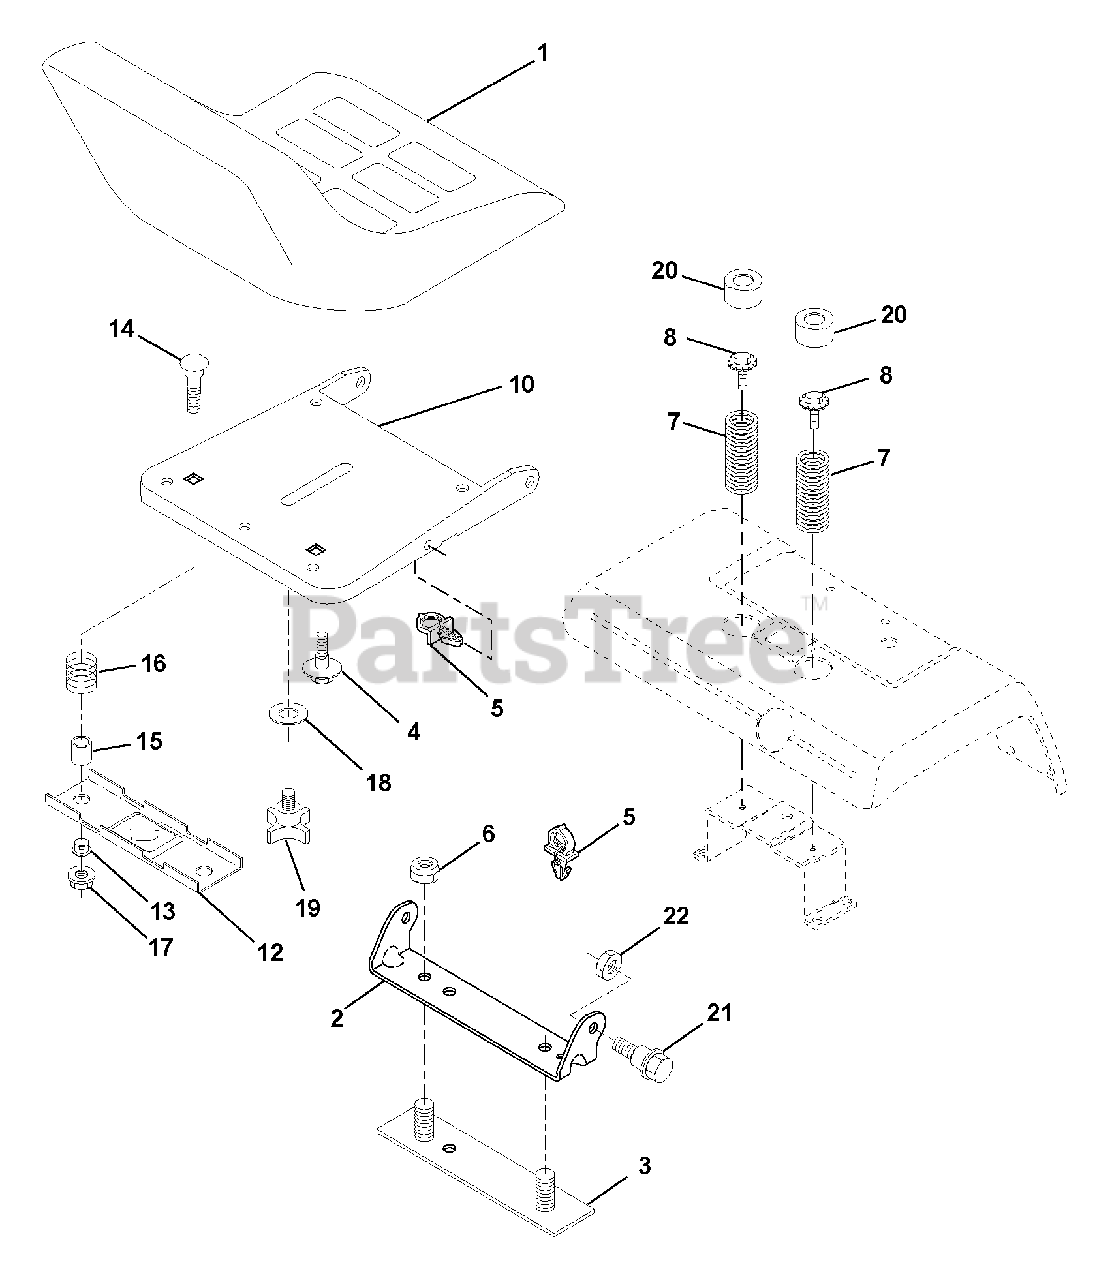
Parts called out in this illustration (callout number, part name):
1	Seat
2	Bracket, Pivot Seat
3	Strap, Fender
4	Bolt, Shoulder 5/16-18 X .62
5	Clip, Push In Hinged
6	Nut, Lock Hex W/Ins. 3/8-16 Unc
7	Spring, Seat Cprsn
8	Screw, Thdrol 5/16-18 X 1/2
9	Washer 13/32 X 1 X 14 Ga.
10	Pan, Seat
12	Bracket, Mounting Switch
13	Bushing, Snap
14	Bolt, Carriage 1/4-20 X 1-3/8
15	Spacer, Split
16	Spring, Cprsn
17	Nut, Lock 1/4 Lge Flg Gr. 5
18	Washer 17/32 X 1-3/16 X 12 Ga.
19	Knob, Seat 1/2-13 Unc
20	Cap, Spring Seat
21	Bolt, Shoulder 5/16-18 Unc
22	Nut, Crownlock 5/16-18 Unc
